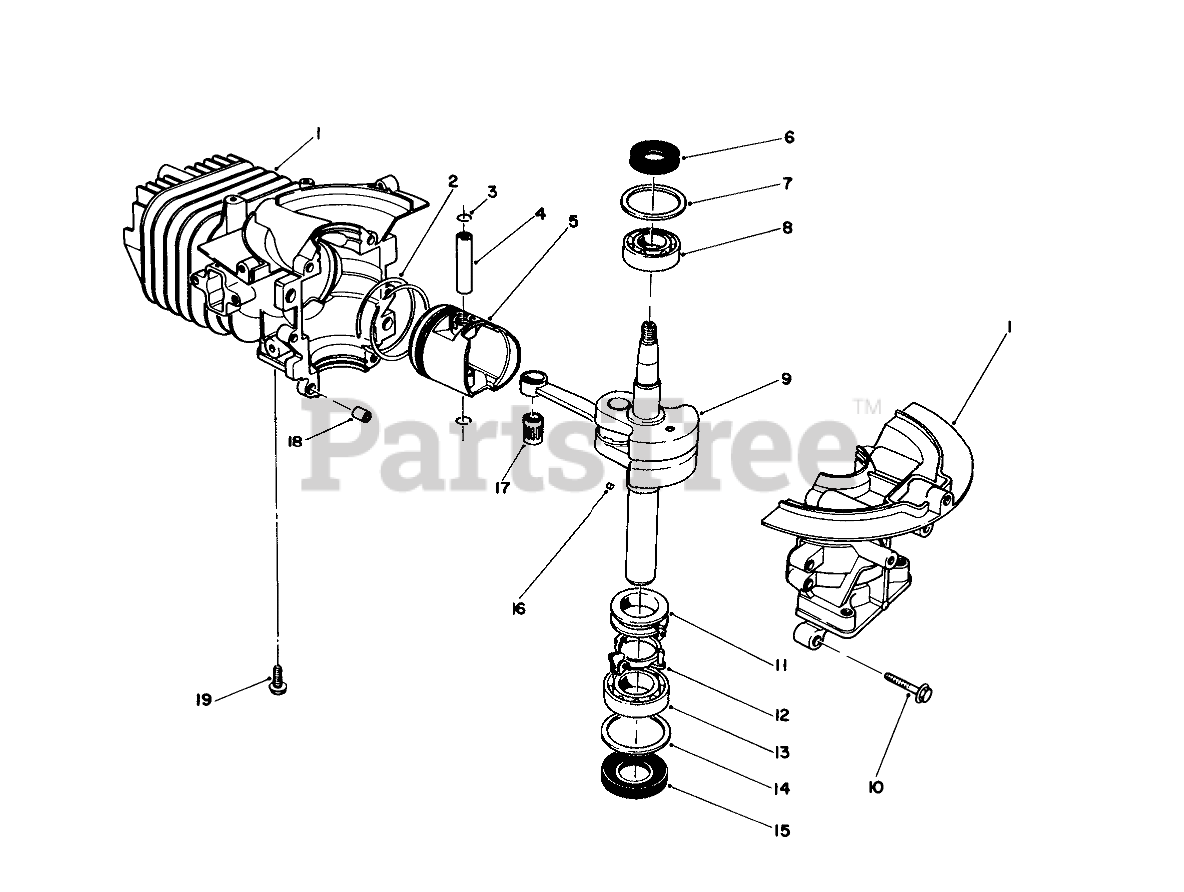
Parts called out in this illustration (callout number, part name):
1	CYL/CRANKCASE ASM
2	RING SET
4	PISTON
5	Piston
6	OIL SEAL
7	WASHER-UPPER
8	BEARING-UPPER
9	CRANKSHAFT
11	SPACER
12	BRACKET
13	LOWER BRG
14	WASHER-LOWER
15	SEAL-OIL
17	BEARING
